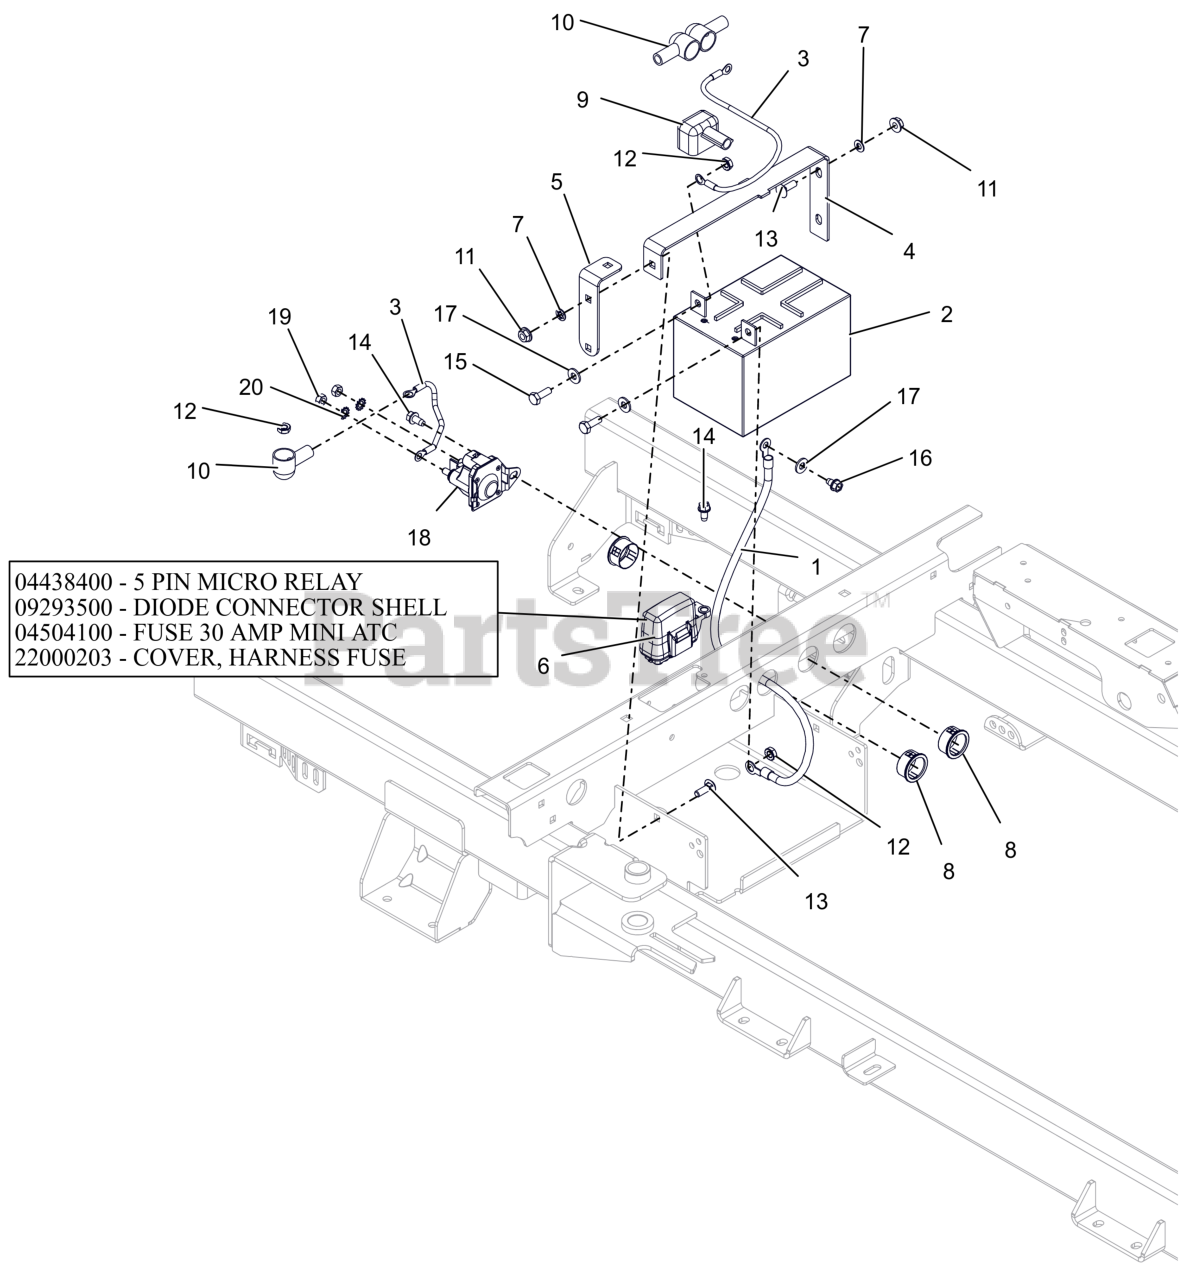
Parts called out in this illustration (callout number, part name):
1	CABLE-NEGATIVE BATTERY 24.00"
2	BATTERY, 12V 12A-190CCA
3	CABLE,POS W/2 1/4 RING 15.0 LG
4	BRKT, BATTERY HOLD-DOWN
5	BRKT, BATTERY HOLD DOWN
6	HARNESS, WIRE-4POS KEY IKON/ZT
6	RELAY,MICRO5 TERML W/RESISTOR
6	DIODE, CONNECTOR SHELL
6	FUSE,30 AMP MINI-ATC
6	COVER, FUSE
7	NUT-PUSH .25X.50 O.D.
8	BSHG, PANEL SNAP .937X1.11X.56
9	INSULATOR
10	BOOT, EYELET TERMINAL
11	NUT-LK-TOP-FLG .250-20 GF ZCC
12	NUT-KEPS .250-20 ZCC
13	BLT, RHSN .25-20X.750 G5 ZCC
14	SCR-TAP .25-20X.50 HWH ZCC
15	BLT, HEX .25-20X.75 G5 ZCC
16	SCR,TAP .25-20X.375 HWH TR ZCC
17	WSHR,FLT .281X.625X.065 ZCC
18	SOLENOID, STARTER (SEALED)
19	NUT-STD M6-1.0 ZCC
20	WSHR,LK-EXT.262X.502X.026 ZCC
